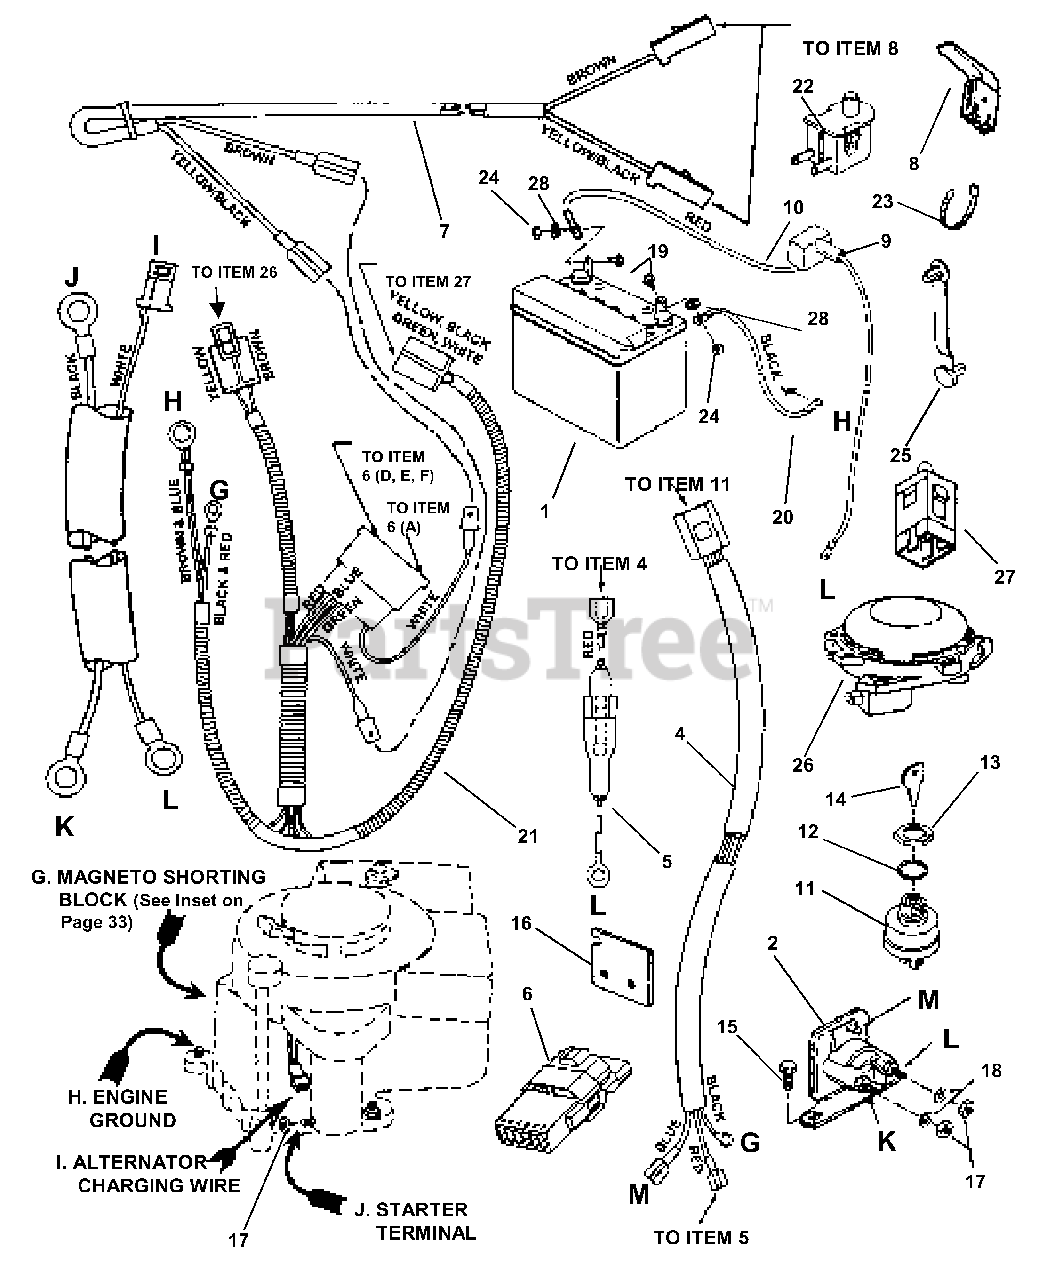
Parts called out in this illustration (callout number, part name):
1	KIT, 12Volt Dry Charge Battery
2	SOLENOID
4	HARNESS, Ignition Wiring (Briggs Engines)
5	HOLDER, Fuse
6	INTERLOCK Module (Briggs)
7	HARNESS (Deck Interlock Wiring)
8	SWITCH, Deck Interlock (NO)
9	COVER, Battery Cable
10	CABLE, Positive (17" Long, Red)
11	SWITCH, Ignition (Used With Electric Start)
12	WASHER, 5/8 Internal Tooth Lock
13	NUT, 5/8-32 Hex
14	KEY, Switch
15	SCREW, 1/4-20 x 1/2" Hex Washer Self-Tap
16	PROTECTOR (25" Models Only!)
17	NUT, 1/4-20 Hex, Grade 5 or B
18	WASHER, 1/4 Internal Tooth Lock
19	SCREW, 1/4-20 x 5/8" Hex Head Cap, Grade 5
20	CABLE, Negative (15" Long)
21	HARNESS, Operator Presence Control (OPC) Wire
22	SWITCH, Seat (12 & 13H.P. Briggs) (NC)
23	TIE, 7" Long Cable
24	NUT, 1/4-20 Hex Center Lock
25	TIE, 2" Long Cable
26	SWITCH, Seat (8 HP & 10 HP Engines) (NC)
27	SWITCH, Operator Presence Control (OPC) Traction (NC/NO)
28	RETAINER, 1/4" Bolt
